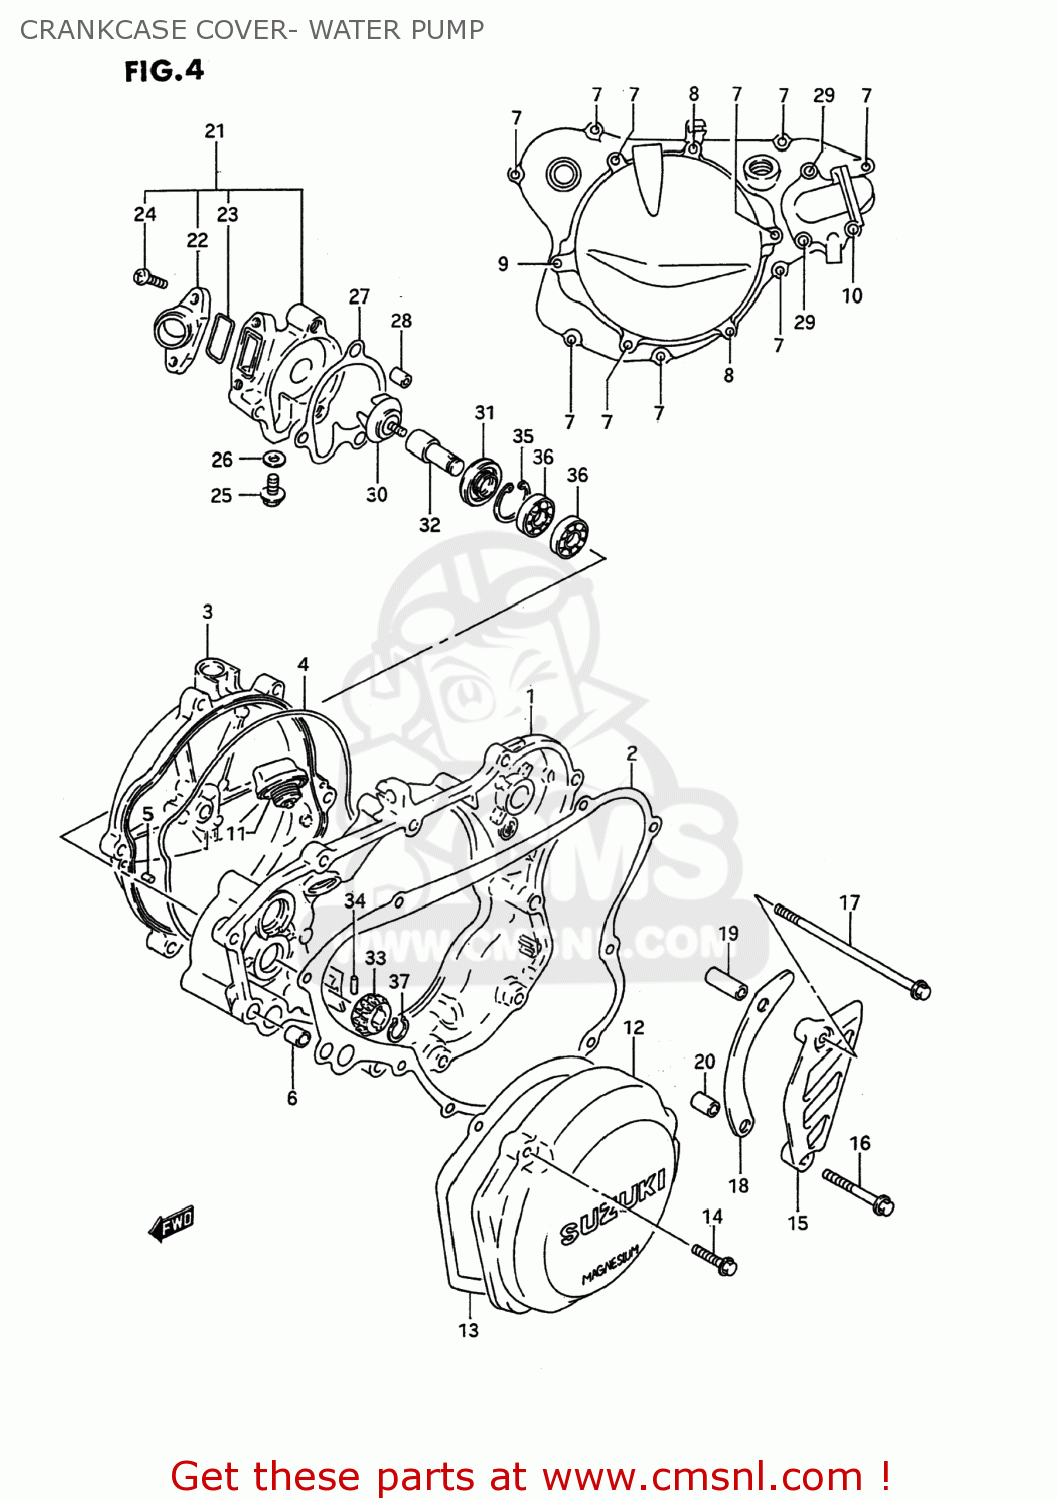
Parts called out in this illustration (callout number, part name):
1	COVER,CLUTCH
2	GASKET,CLUTCH COVER (NAS)
3	COVER,CLUTCH,OUTER
4	O RING,CLUTCH COVER OUTER
5	PIN
6	PIN
7	BOLT
8	BOLT
9	BOLT
10	BOLT
11	PLUG SET
12	COVER
13	GASKET,MAGNETO COVER (NAS)
14	BOLT
15	COVER,SPROCKET
16	BOLT
17	BOLT
18	PLATE,FR CHAIN GUIDE
19	SPACER(6.5X10.5X25)
20	SPACER(6.5X10.5X12)
21	CASE,WATER PUMP
22	CONNECTOR
23	O RING,WATER PUMP CONNECTOR
24	SCREW
25	BOLT
26	WASHER
27	GASKET,WATER PUMP CASE (NAS)
28	PIN
29	BOLT
30	IMPELLER,WATER PUMP
31	SEAL,WATER PUMP OIL
32	SHAFT,WATER PUMP
33	GEAR,WATER PUMP DRIVEN
34	PIN(3X13.8)
35	CIRCLIP
36	BEARING
37	CIRCLIP,10MM
